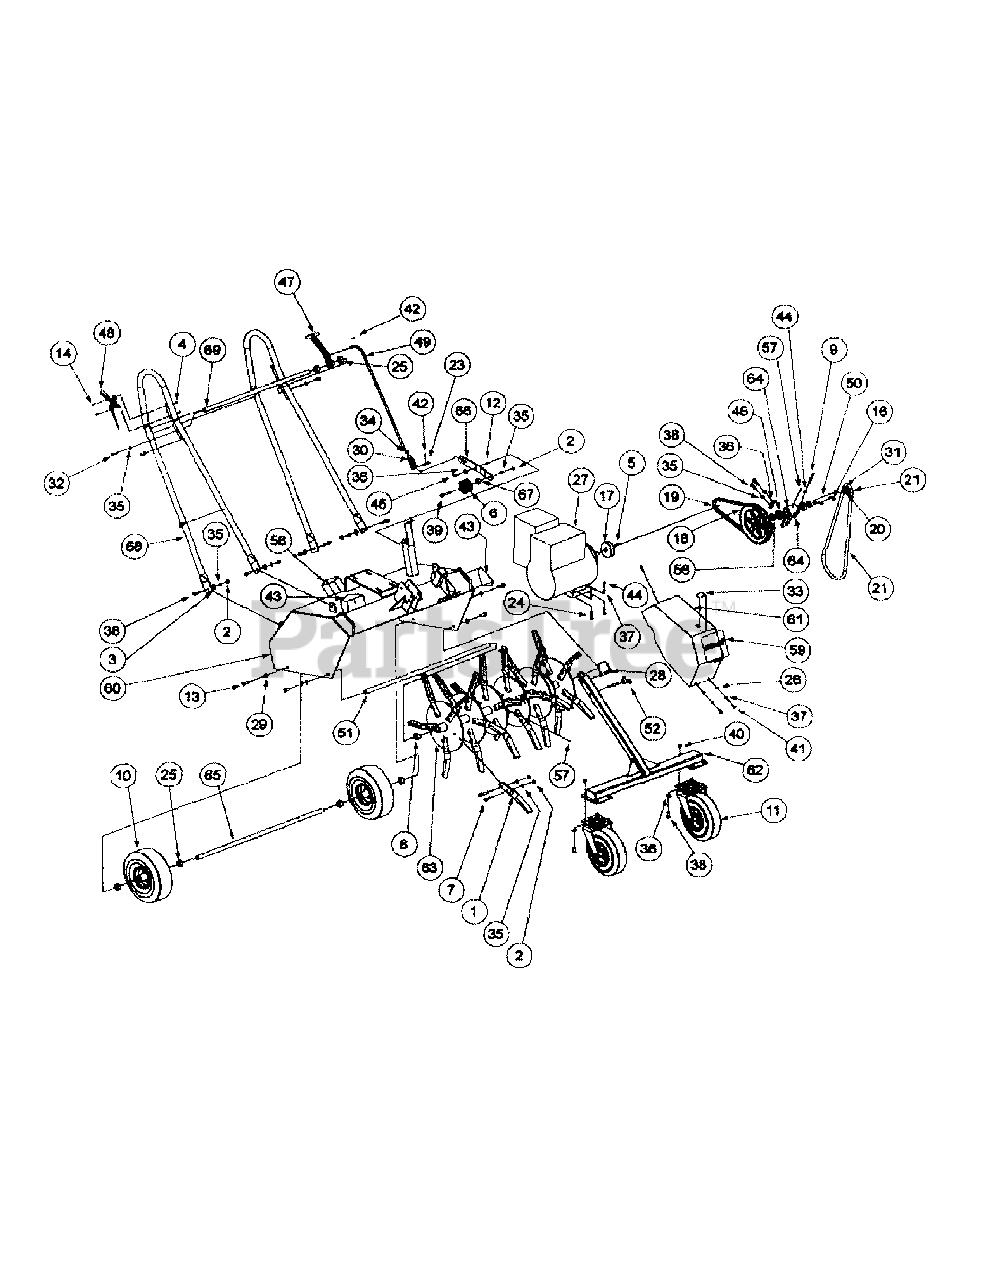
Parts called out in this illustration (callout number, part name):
1	Open Spoon 1/2"
2	Hex Nut, 3/8-16
3	Flat Washer, USS 3/8 Zinc
4	Lock Nut, Nylon Insert, #10-24
5	Key, 3/16" x 1"
6	Idler, Flat 3616
7	Capscrew, 3/8-16 x 1-3/4"
8	Bushing, Flange, Sintered, Bronze
9	Cap Screw, Square Head, 5/16-18 x 2-1/2
10	Rear, Wheel, 410/350 x 4-2Ply, White
11	Caster Wheel
12	Bushing, 1/2 x 3/8 x 1/4, Bronze
13	HHCS, 7/16-14, 1, Yellow Zinc
14	Screw, Round Head, Machine, 10-24 x 1/2
15	Clamp, To Hold Tubing on Handle
16	Woodruff Key, 3/16 x 3/4, #606
17	Small Pulley
18	Large Pulley
19	V Belt
20	Sprocket, 40BS-10 x 3/4" BOR
21	Chain #40 W/Master Link
22	Master Link, #40
23	Clevis Pin, 3/8 x 1 1/8, Zinc
24	Carrige Bolt, 5/16-18 x 1-1/2
25	Shaft Color, .760" x Bore w/SS Plate
26	Flat Washer, 5/16, SAE, Yellow Zinc
27	Engine, Briggs & Stratton, 5 HP
28	Lynch Pin, 3/8 x 2-1/4, Zinc
29	Lock Washer, 7/16, Zinc
30	Yoke, 3/8-24 Forged
31	Cap, Screw, Socket Set, 5/16-18 x 1/4
32	HHCS, Standard, 3/8-16 x 3/4, Zinc
33	Decal, "Grease Daily"
34	Hex Nut, 3/8-24, Yellow
35	Lock Washer, 3/8 Zinc
36	Flat Washer, 3/8, SAE, Yellow Zinc
37	Lock Washer, 5/16, Zinc
38	HHCS, Standard, 3/8-16 x 1, Zinc
39	HHCS, Standard, 3/8-16 x 2, Zinc
40	Lock Nut, Nylon Insert, 3/8-16
41	HHCS, Standard, 5/16-18 x 1/2, Zinc
42	Cotter Pin, 3/32 x 3/4, Zinc
43	Decal, Rotary "Danger-Keep Hands"
44	Hex Nut, 5/16-18, Yellow
45	Shoulder Bolt, Socket, 3/8 x 3/8 Zinc
46	Bearing, Single, Seal, 1630-RS
47	Handle, Throw-Out
48	Throttle Cable
49	Belt Tensioner Rod, Zinc Plated
50	Jackshaft Complete
51	Reel Shaft
52	Pin, Release Quick 3/8 Dia X3.
54	Plate Base
55	Carton Top Cap & Top Frame
56	Flat Washer, .06, .776, 1.25, SS
57	Grease Fitting, 1/4-28 x 3/16 STR
58	Decal, "Made In America
59	Decal, "MTD PRO"
60	Housing Assembly
61	Belt & Chain Guard Assembly
62	Front Support Assembly
63	Reel Assembly
64	Jackshaft Bearing Mount Assembly
65	Right Rear Wheel Axle
66	Belt Tensioner
67	Spacer, Belt Tensioner
68	Handle Assembly w/Brace
69	Handle Strut
